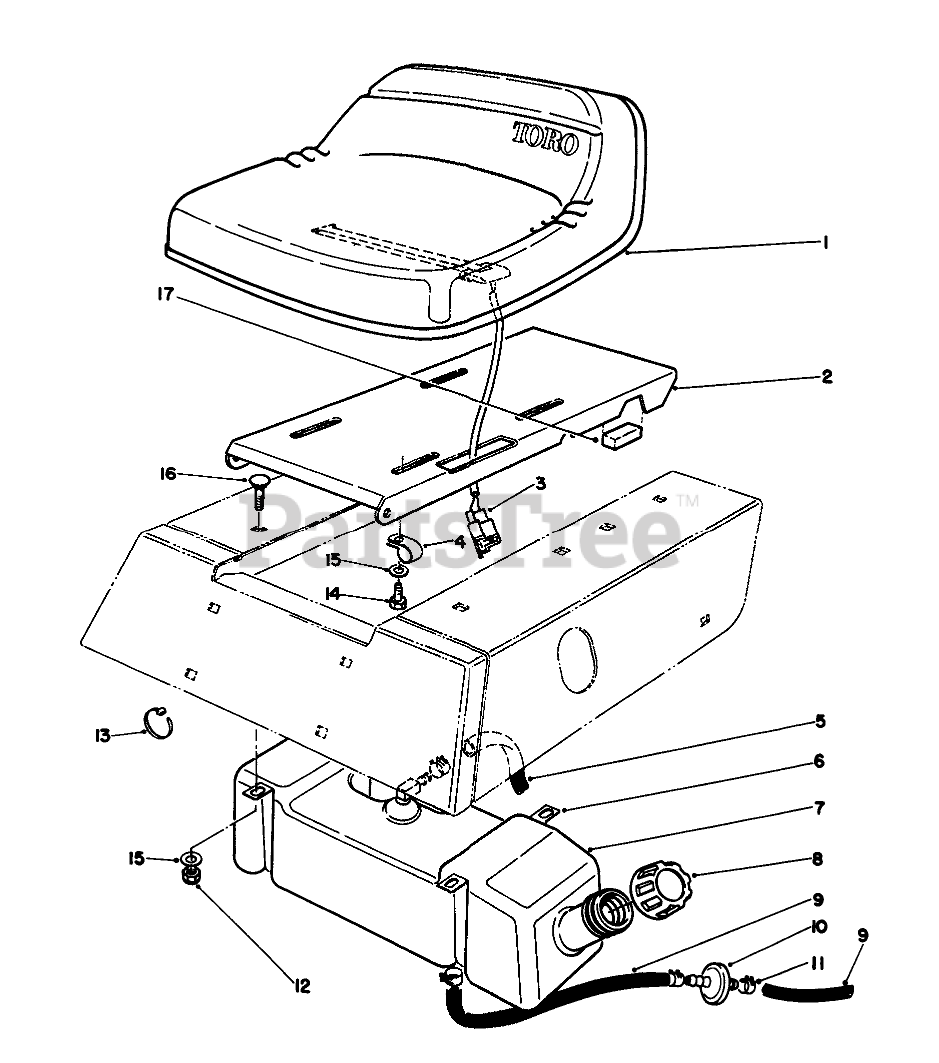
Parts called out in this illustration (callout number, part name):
1	Seat
2	BASE - SEAT
3	SWITCH-SEAT
4	CLIP-FUEL LINE
5	HOSE-FUEL
6	STRAP-GAS TANK
7	TANK-GAS
8	GAS CAP ASM
9	HOSE-FUEL
10	FILTER-FUEL
11	CLAMP-HOSE
12	NUT-LOCK, NI
13	TIE-CABLE
14	SCREW-HH
15	WASHER-PLAIN
16	SCREW-CARR
17	PAD-ISOLATOR
